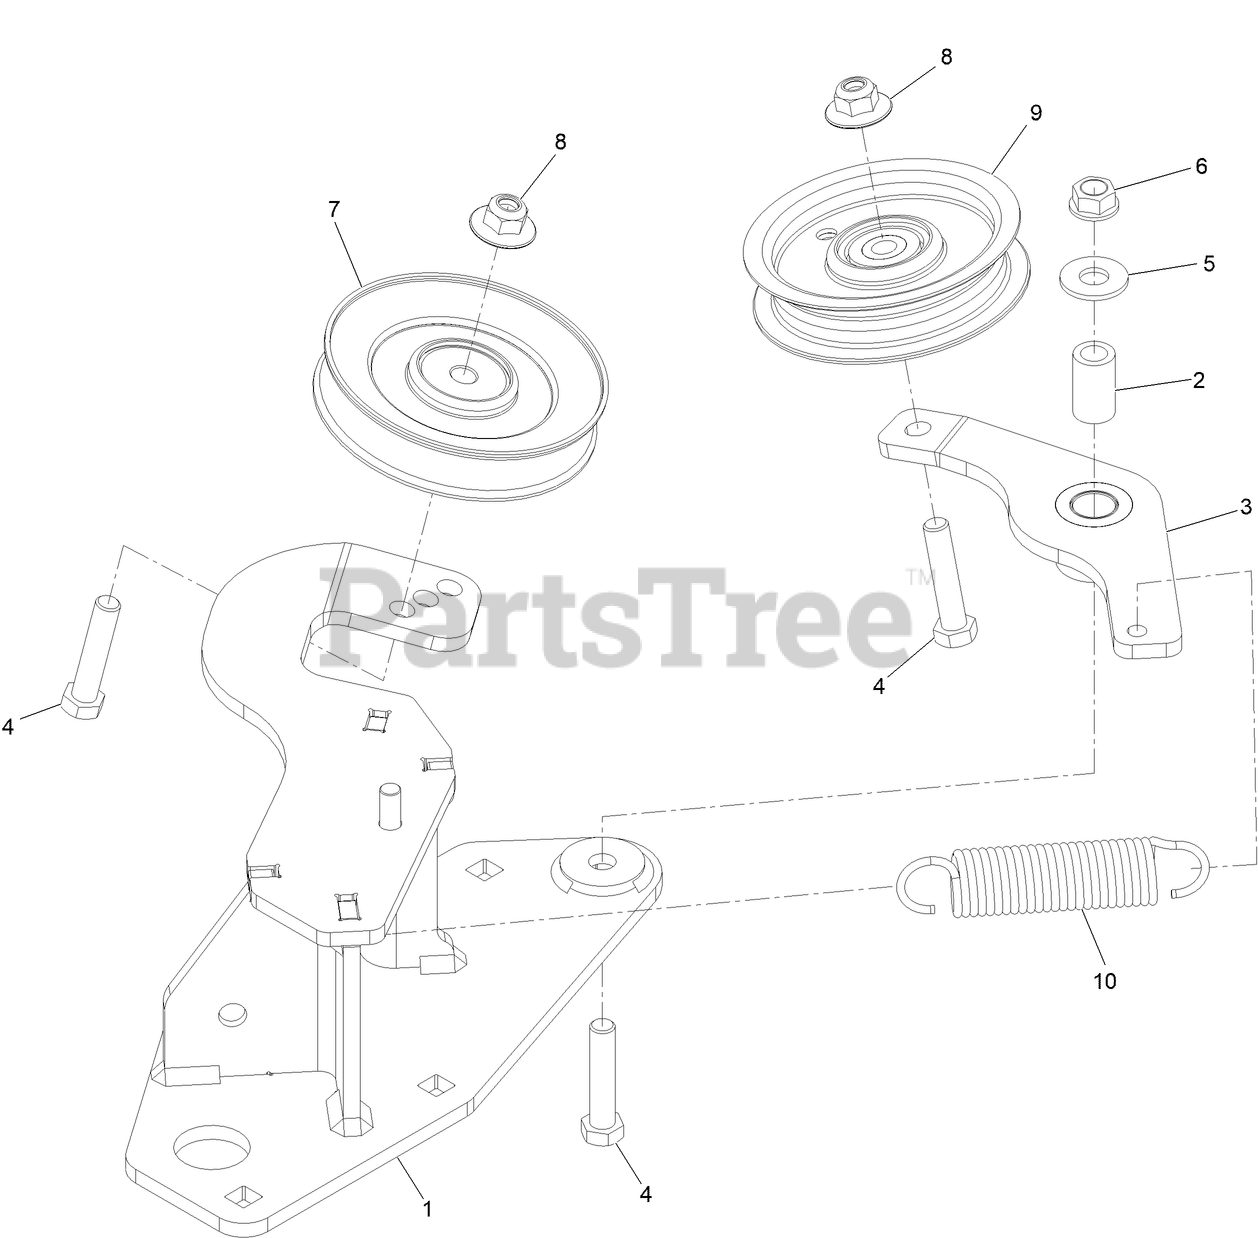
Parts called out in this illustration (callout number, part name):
1	Idler ASM-Blower [black]
2	BUSHING-PIVOT, IDLER
3	IDLER ASM
4	SCREW-HH
5	WASHER-FLAT
6	NUT-HHF, WHIZ
7	PULLEY-IDLER
8	Nut-Nyloc 3/8-16 Flg
9	PULLEY-IDLER, FLAT
10	SPRING-EXTENSION
